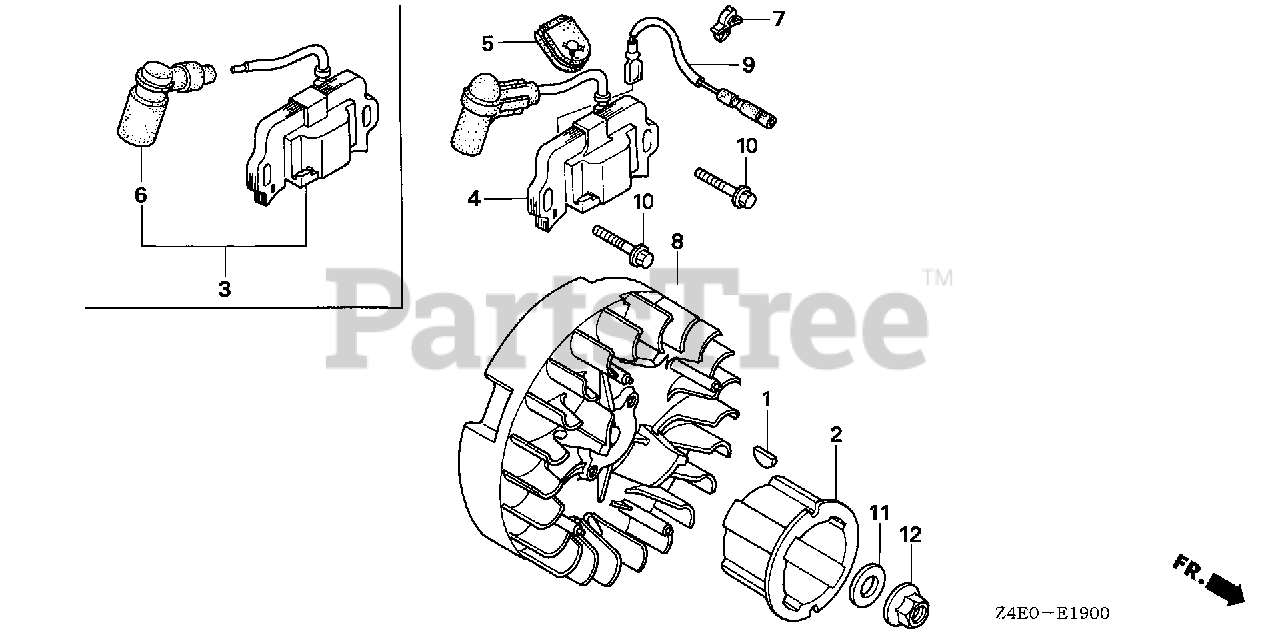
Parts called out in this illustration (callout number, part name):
1	KEY, SPECIAL
4	COIL ASSY., IGNITION
5	GROMMET, WIRE
7	CLIP, IGNITION WIRE (8MM)
9	WIRE, STOP SWITCH
10	BOLT, FLANGE (6X20) (CT200)
11	WASHER (12MM)
12	NUT, FLANGE (12MM)
